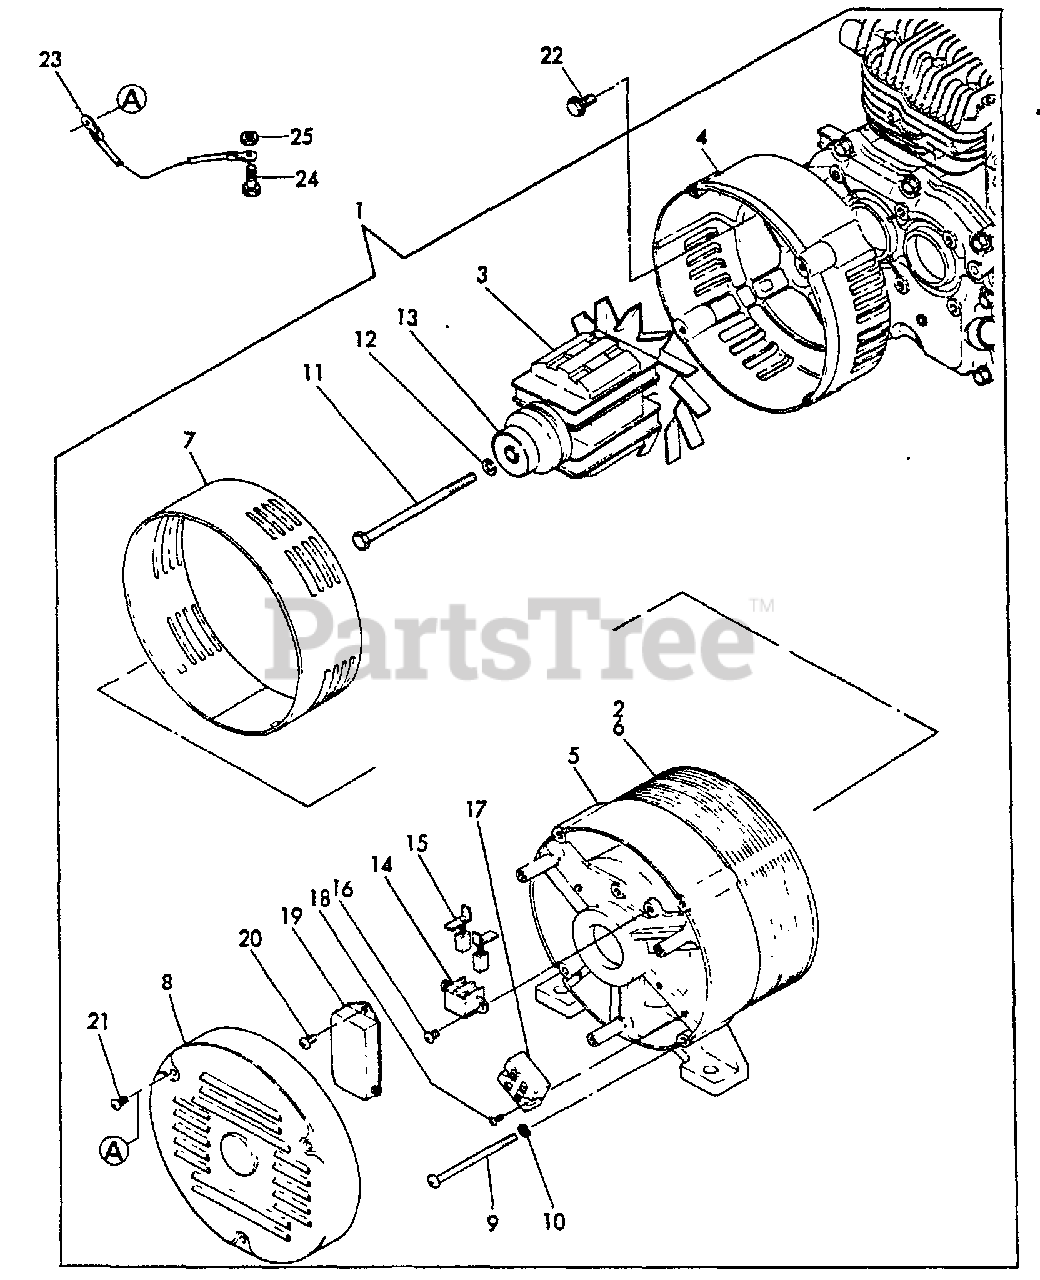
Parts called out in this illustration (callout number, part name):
1	GENERATOR 3.8KVA
2	STATOR ASSY
3	ROTOR ASSY
4	COVER - FRONT
5	COVER - REAR
6	STATOR
7	BAND
8	COVER, END
9	BOLT, THROUGH
10	LOCKWASHER - 6
11	BOLT
12	LOCKWASHER - 10
13	BEARING, BALL
14	HOLDER, BRUSH
15	BRUSH ASSY
16	SCREW - 4X10
17	TERMINAL
18	SCREW - 5X14
19	A.V.R.
20	SCREW - 5X14
21	SCREW - 4X10
22	BOLT - 8X20 -- PLATED
23	LEAD - GROUND
24	BOLT - 6X16 -- PLATED
25	LOCKNUT - 6 -- PLATED
